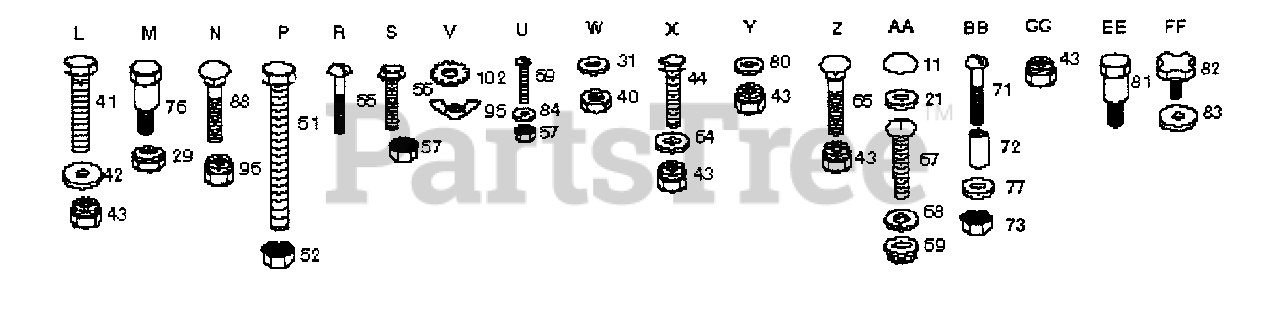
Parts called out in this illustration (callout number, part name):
21	Washer, Snap Cap
29	Nut, Crownlock 5/16-18
31	Washer 9/32 x 3/4 x 16 Ga.
40	Nut, Hex 1/4-20
41	Bolt, Hex 3/8-16 x 3/4
42	Washer 13/32 x 13/16 x 12 Ga.
43	Nut, Crownlock 3/8-16
44	Bolt, Hex 3/8-16 x 1
51	Bolt, Hex 3/8-16 x 1-1/4
52	Nut, Keps 3/8-16
55	Screw, Hex Head Self Tapping #10-16 x 1/2 Type B
56	Bolt, Hex 5/16-18 x 3/4 Gr. 5
57	Nut, Keps 5/16-18
59	Screw, Truss Hd. 5/16-18 x 3/4
64	Washer 13/32 x 1-1/4 x 12 Ga.
65	Bolt, Carriage 3/8-16 x 3/4
67	Screw, Cross Recess Pan Hd. Mach. #10-24 x 1/2
68	Washer, Lock #10
69	Nut, Weld
71	Screw, Machine Cross Recess #10-24x1-1/4
72	Spacer, Split #10 x 3/4
73	Nut, Keps #10 - 24
76	Bolt, Shoulder
77	Washer 7/32 x 1/2 x 18 Ga.
80	Washer 13/32 x 1 x 14 Ga.
81	Bolt, Shoulder 5/16 x 18 UNC x .62
82	Knob - 1/2
83	Washer 17/32 x 13/16 x 12 Ga.
84	Washer 11/32 x 11/16 x 16 Ga.
88	Bolt Carriage 1/4 - 20 x 1-1/4
95	Wing Nut 1/4-20
96	Nut, Hex Large Flange Lock
102	Washer, Lock, Int./Ext.1/4
